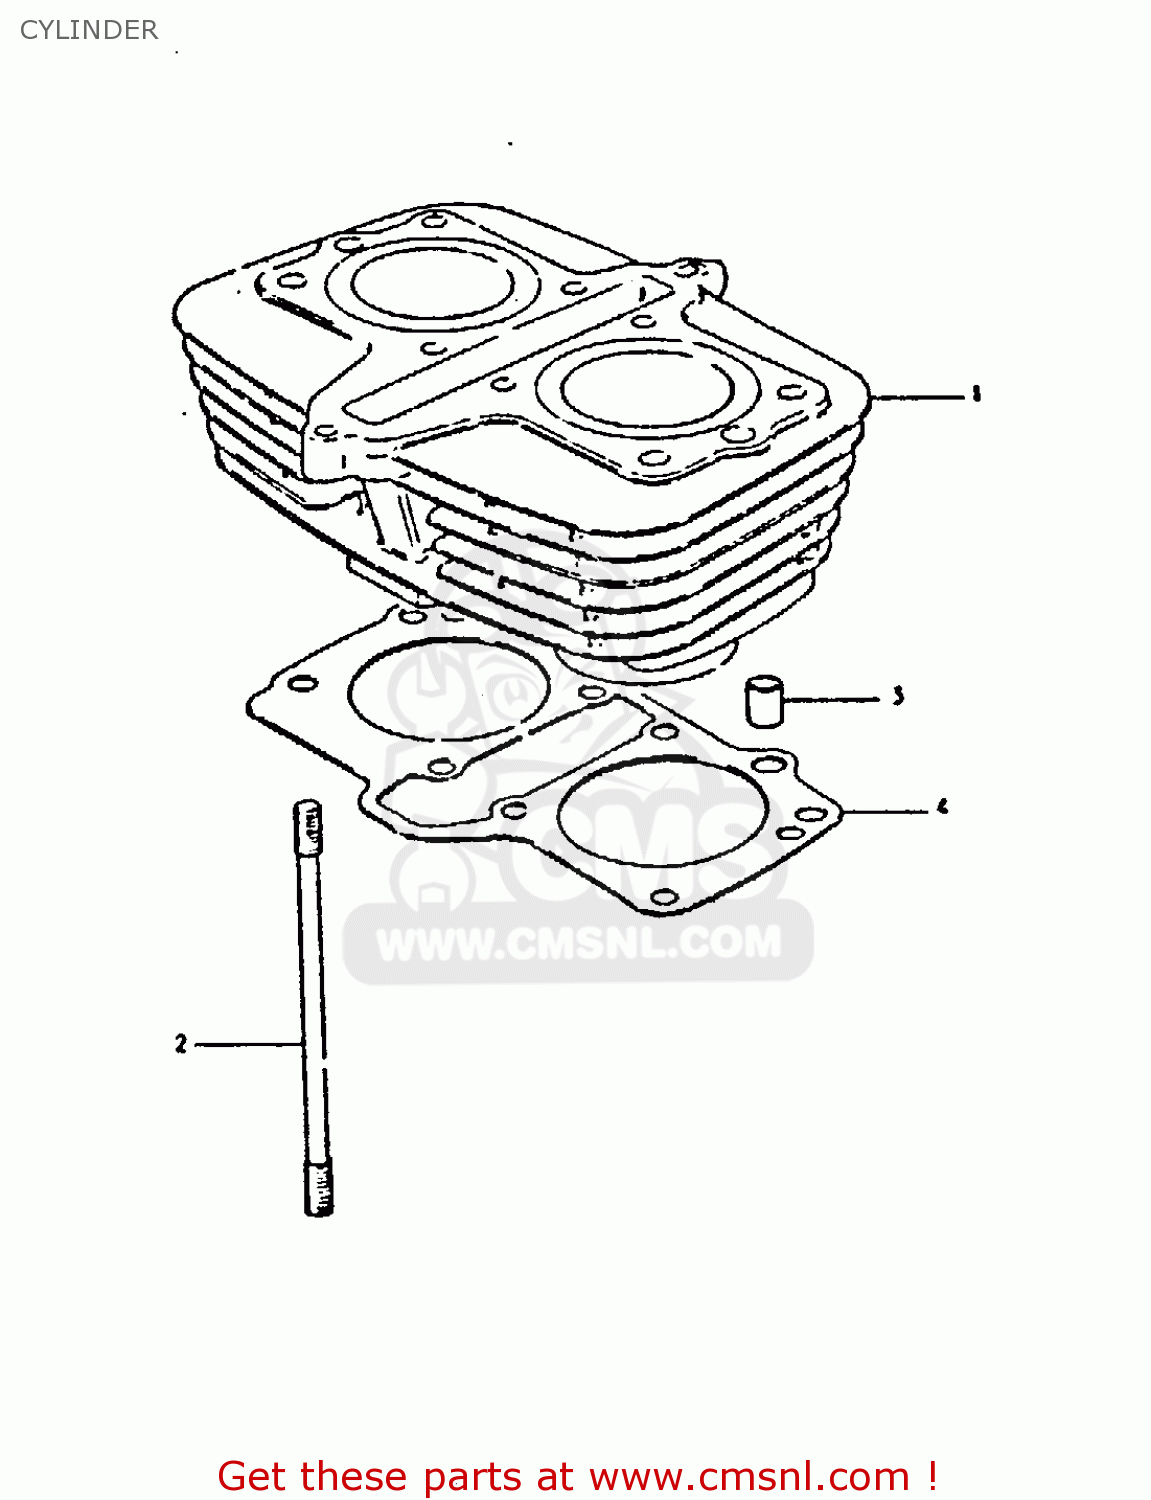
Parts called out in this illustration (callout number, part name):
1	CYLINDER
2	STUD
3	PIN
4	GASKET,CYLINDER (MCA)
